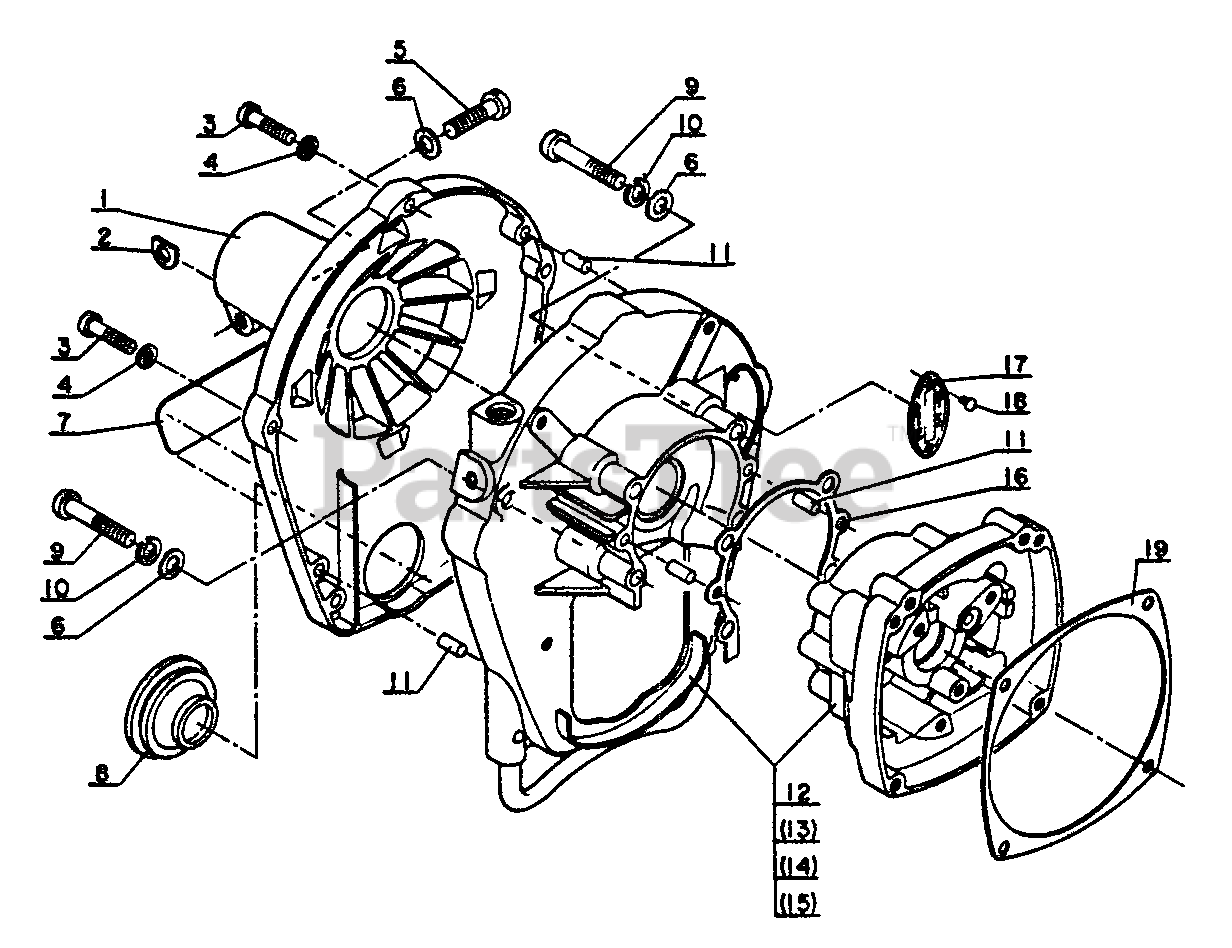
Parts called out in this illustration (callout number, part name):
1	CASE, FAN
3	SCREW - 4X18
4	WASHER - 4
5	BOLT - 5X20
6	WASHER - 5
7	NAME PLATE
8	SEAL, DUST
9	SCREW - 5X18
10	LOCKWASHER - 5
11	PIN - LOCATING
12	CRANKCASE KIT
14	STAND
16	GASKET, CRANKCASE
17	PLATE, MODEL
18	RIVET
19	GASKET, STARTER
